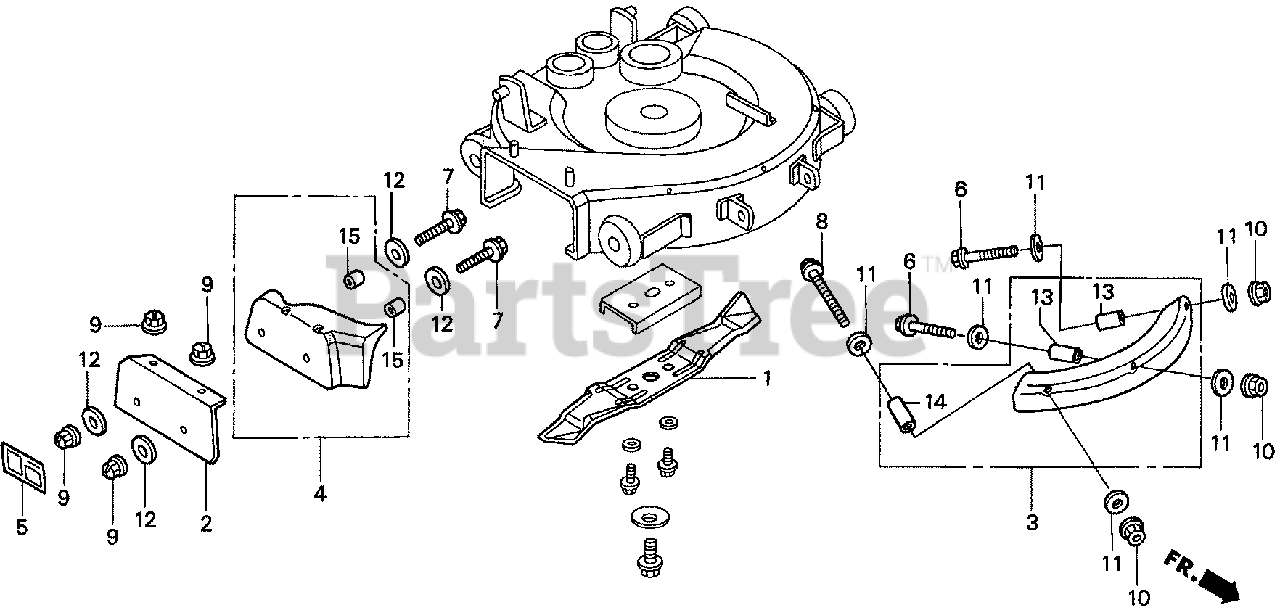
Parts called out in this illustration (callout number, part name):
1	BLADE, MULCHING (NOT AVAILABLE)
2	PLATE, COVER (NOT AVAILABLE)
3	GUIDE A, SWIRL (NOT AVAILABLE)
4	GUIDE B, SWIRL (NOT AVAILABLE)
5	LABEL A, WARNING (ENGLISH)
6	BOLT, FLANGE (6X40)
7	BOLT, FLANGE (8X35)
8	BOLT, FLANGE (6X55)
9	NUT, SELF-LOCK (8MM) (CLINCH)
10	NUT, SELF-LOCK (6MM)
10	NUT, LOCK (6MM)
11	WASHER, FLAT (6MM)
12	WASHER, FLAT (8MM)
13	COLLAR A (N/A: SEE ASSEMBLY)
14	COLLAR B (N/A: SEE ASSEMBLY)
15	COLLAR C (N/A: SEE ASSEMBLY)
